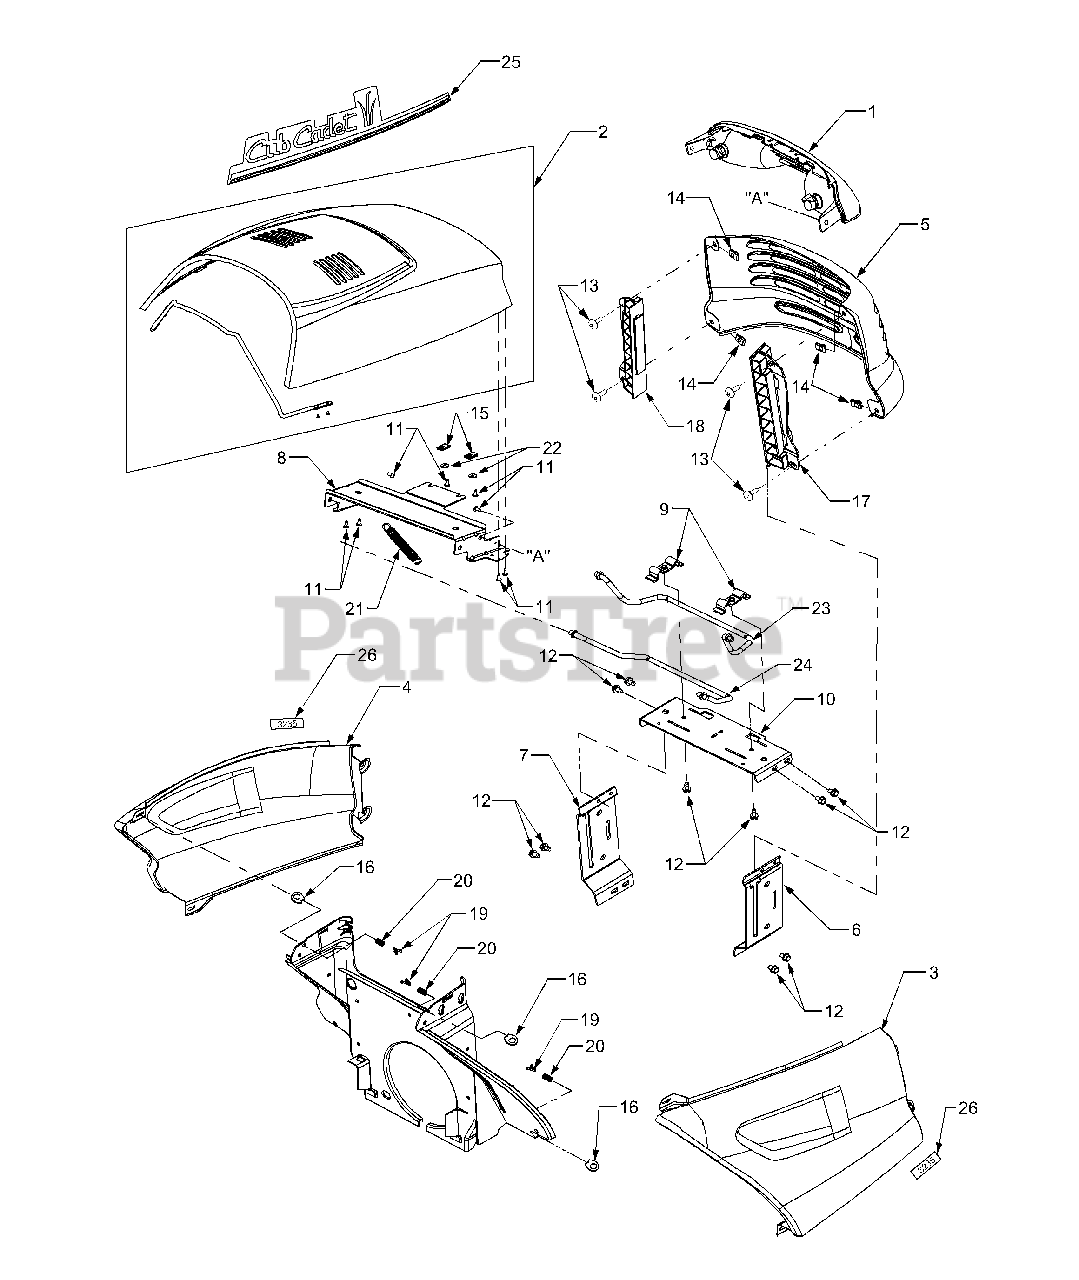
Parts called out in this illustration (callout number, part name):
1	Headlight Assembly (Lens glued to reflector)
2	Hood w/Support Rod Assembly
3	Side Panel, RH
4	Side Panel, LH
5	Grille, Series 3000
6	Support, Grille - RH
7	Support, Grille - LH
8	Bracket, Upper Hood
9	Bracket, Rod Retainer
10	Support, Hood
11	Screw, Truss Hd, Tapp, #10-16 x .5
12	Screw, Hex Wash. Hd. Tapp 5/16-18 x .5
13	Screw, Phil. Pan Hd. 1/4-20 x .75
14	Nut, U Type Speed, 1/4-20
15	Nut, U-type Speed, #10
16	Latch, 1/4 Turn
17	Mount, Side Panel/Grille RH
18	Mount, Side Panel/Grille LH
19	Clip, Spring
20	Spring, Compression
21	Spring, Extension
22	Washer, Flat, .194 x .62 x .063
23	Rod, Upper Hood
24	Rod, Lower Hood
25	Graphic, Hood - RH
26	Graphic, 3235
